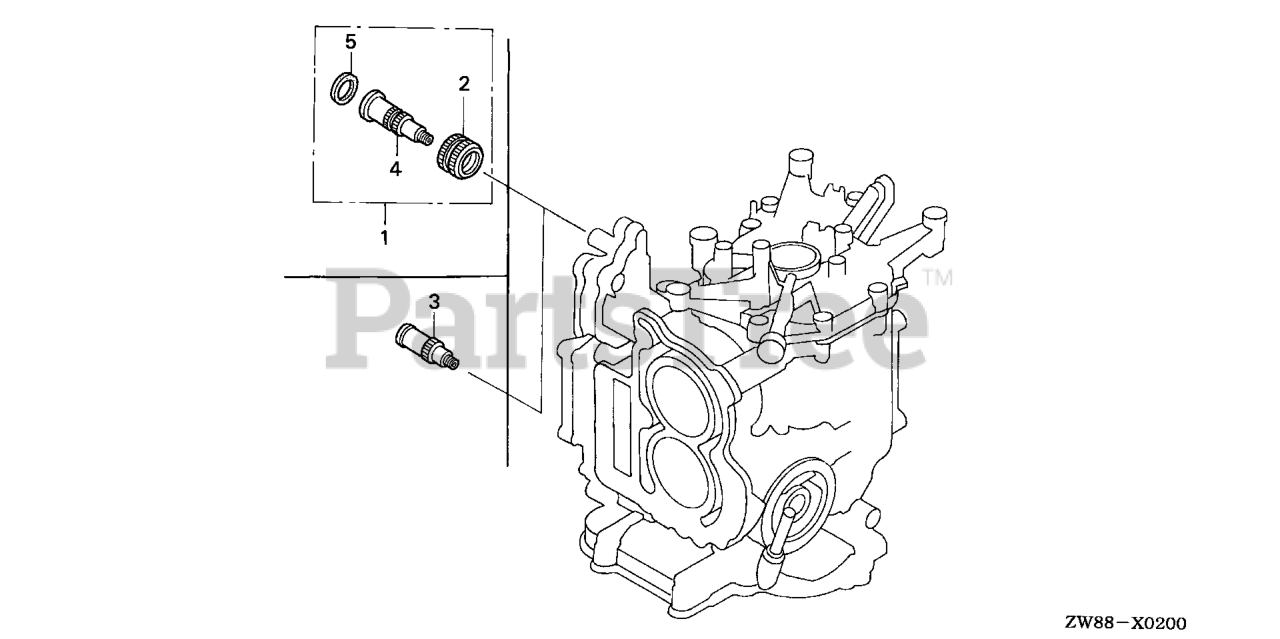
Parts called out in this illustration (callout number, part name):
1	JOINT KIT, WATER HOSE
2	NUT, WATER MOUTH Use from Frame SN 1000929.
3	JOINT, WATER HOSE
4	JOINT, WATER HOSE
5	SEAT, WATER MOUTH Use from Frame SN 1000929.
